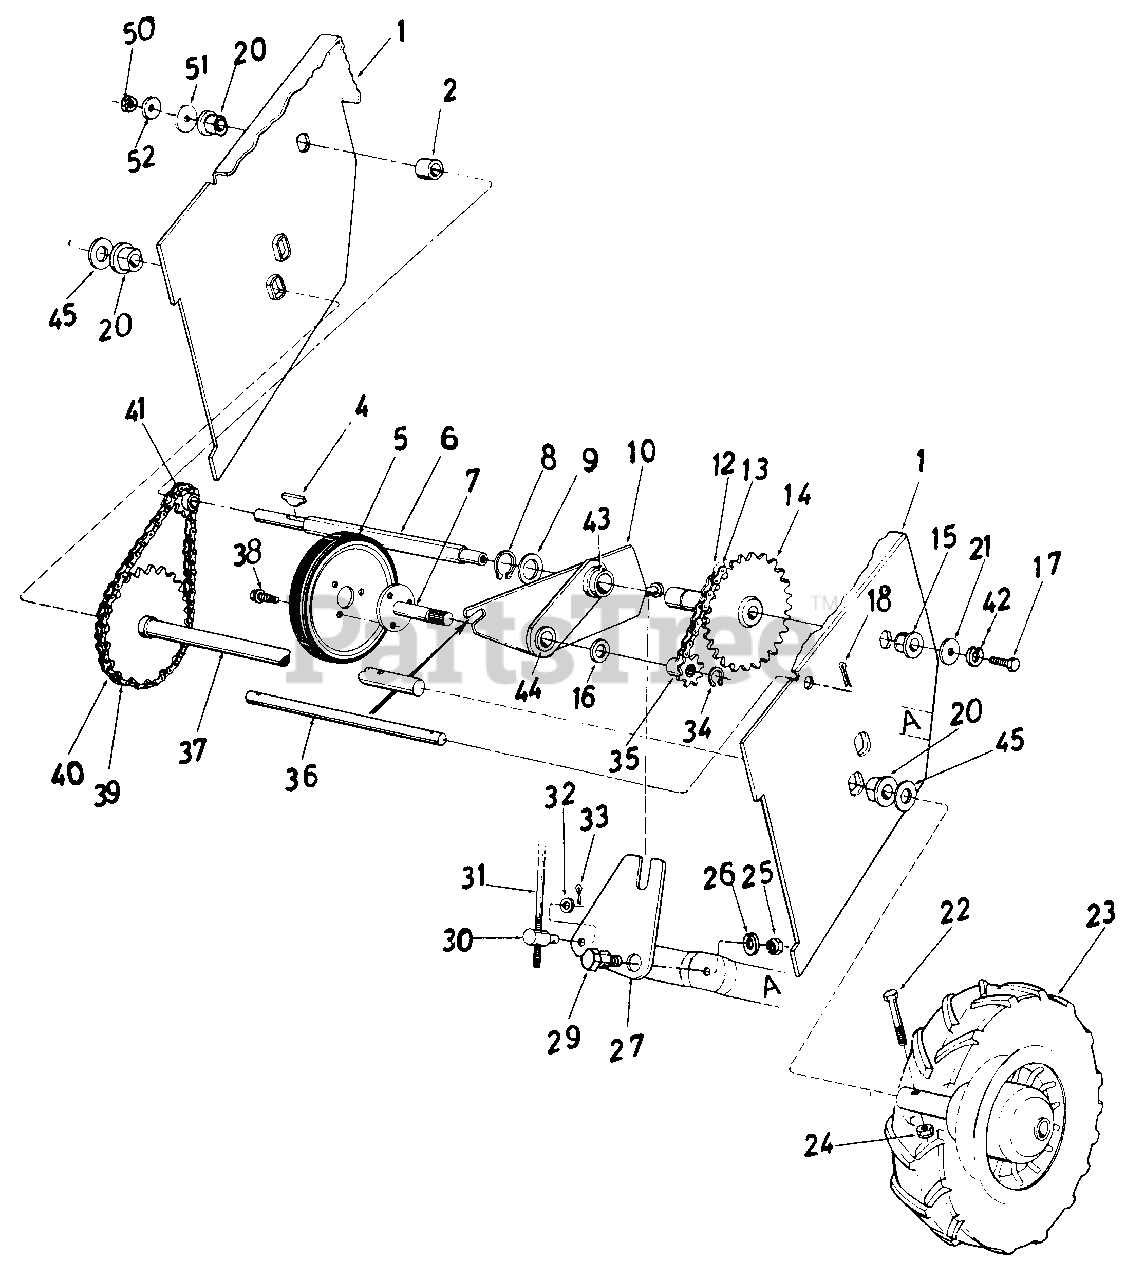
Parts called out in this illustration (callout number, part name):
1	Frame Ass'y.
2	Spacer .50" I.D. x .75" O.D. x.78" Lg.
4	#4 Hi-Pro Key 3/32 x 518" Dia.
5	Friction Wheel Ass'y.
6	Hex Shaft
7	Friction Wheel Mounting Plate Ass'y.
8	Snap Ring 1.00" Dia. Shaft
9	Fl-Wash. 1.00" x 1.63" O.D. x .03
10	Sliding Bracket Ass'y.
12	#41 Chain 1/2" Pitch x 35 Links
13	Master Link for #41 Chain
14	32 Teeth Sprocket Ass'y.
15	Hex Flange Brg. .630" I.D.
16	Fl-Wash. .62" I.D. x 1.00" O.D. x .06
17	Hex Lock Bolt 5/16-18 x .62" Lg.*
18	Cotter Pin 3/32" Dia. x .75" Lg.*
20	Flange Brg. w/Flats .755" I.D.
21	Fl-Wash. .34" I.D. x 1.12" O.D. x .125
22	Hex Bolt 5/16-24 x 1.50" Lg.
23	Wheel Ass'y. Comp.-L.H. 12.5 x 3.5
24	Hex Ins. Jam L-Nut 5/16-24 Thd.
25	Hex Jam Nut 3/8-16 Thd.*
26	L-Wash. 3/8" I.D.*
27	Shifting Linkage Bracket
29	Shld. Bolt .625" Dia. x .170" Lg.
30	Adjustment Ferrule
31	Shifting Rod 5116" Dia. x 32.50" Lg.
32	Fl-Wash. .34" I.D. x .64" O.D. x .06
33	Cotter Pin 3/32" Dia. x .75" Lg.*
34	Snap Ring .562" Dia. Shaft
35	Sprocket 7 Teeth x .50" Pitch
36	Shaft .50" Dia. x 9.50" Lg.
37	32 Teeth Wheel Axle Ass'y.
38	Hex Wash. Hd. Self-Tap Scr. 5/16-24 x .50" Lg.
39	#420 Chain 1/2" Pitch x 39 Links
40	Master Link for #420 Chain
41	8 Teeth Center Sprocket
42	L-Wash. 5116" I.D.
43	Plastic Bearing
44	Bronze Bearing
45	Fl-Wash. .76" I.D. x 1.49 O.D.
50	Hex Ins. L-Nut 1/2-20 Thd.
51	Fl-Wash. .53 I.D. x 1.25 O.D. x .10
52	Bell-Wash. .50 I.D. x 1.0 O.D. x .075
